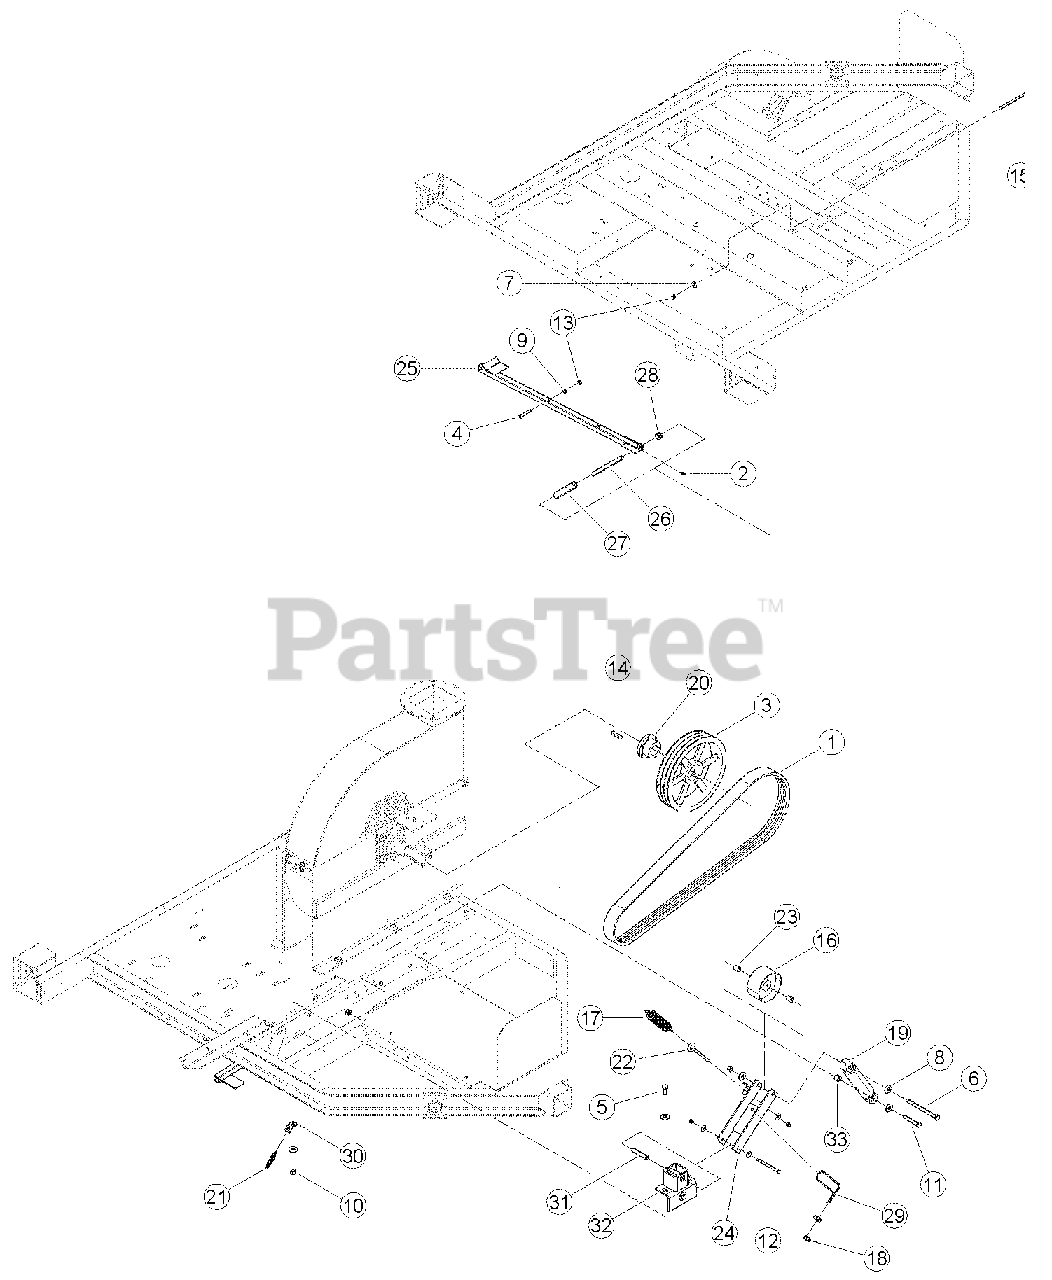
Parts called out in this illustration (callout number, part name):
1	BELT, 3B90 BANDED
2	FITTING, 1/4 SELF-TAP GREASE
3	SHEAVE, 3BQ12.4 SK
4	BOLT, 3/8 X 2 HEX HD GR5 ZP
5	BOLT, 1/2 X 1-1/4 HHCS NC ZP
6	BOLT, 1/2 X 6-1/2 HCS GR5 ZP
7	WASHER, 3/8 FLAT ZP
8	WASHER, 1/2 FLAT ZP
9	NUT, 3/8 HEX NC ZP
10	NUT, 1/2 CENTERLOCK GRB ZP
11	BOLT, 1/2 X 3 HEX HD GR5 ZP
12	BOLT, 3/8 X 4-1/2 HHCS GR5 NC ZP
13	NUT, 3/8 NE NYLOCK ZP
14	KEY, 3/8 SQUARE X 2 LONG PLAIN
15	BOLT, 3/8 X 7-1/2 HHCS GR5 NC ZP
16	PULLEY, IDLER 5 X 2.50
17	SPRING, 7-3/4 EXTENSION
18	CLAMP, 3/16 CABLE
19	ABSORBER, IDLER SHOCK
20	BUSHING, SK 1-3/4
21	SPRING, LT. EXT. .555 OD. X 2.75 LONG
22	EYEBOLT, 3/8 X 5, 4-1/4 THD ZP
23	SPACER, .75 X .90
24	WELDMENT, IDLER ARM
25	WELDMENT, CHIPPER CLUTCH PEDAL
26	SPACER, .63 X 6.44
27	SPACER, 1.0 X 4.25
28	SPACER, 1.0 X .50
29	CABLE, 3/16 X 24-1/2
30	ANGLE, SPRING ANCHOR
31	SPACER, .63 X 3.06
32	WELDMENT, IDLER SUPPORT
33	SPACER, 7/8 X 3/4
